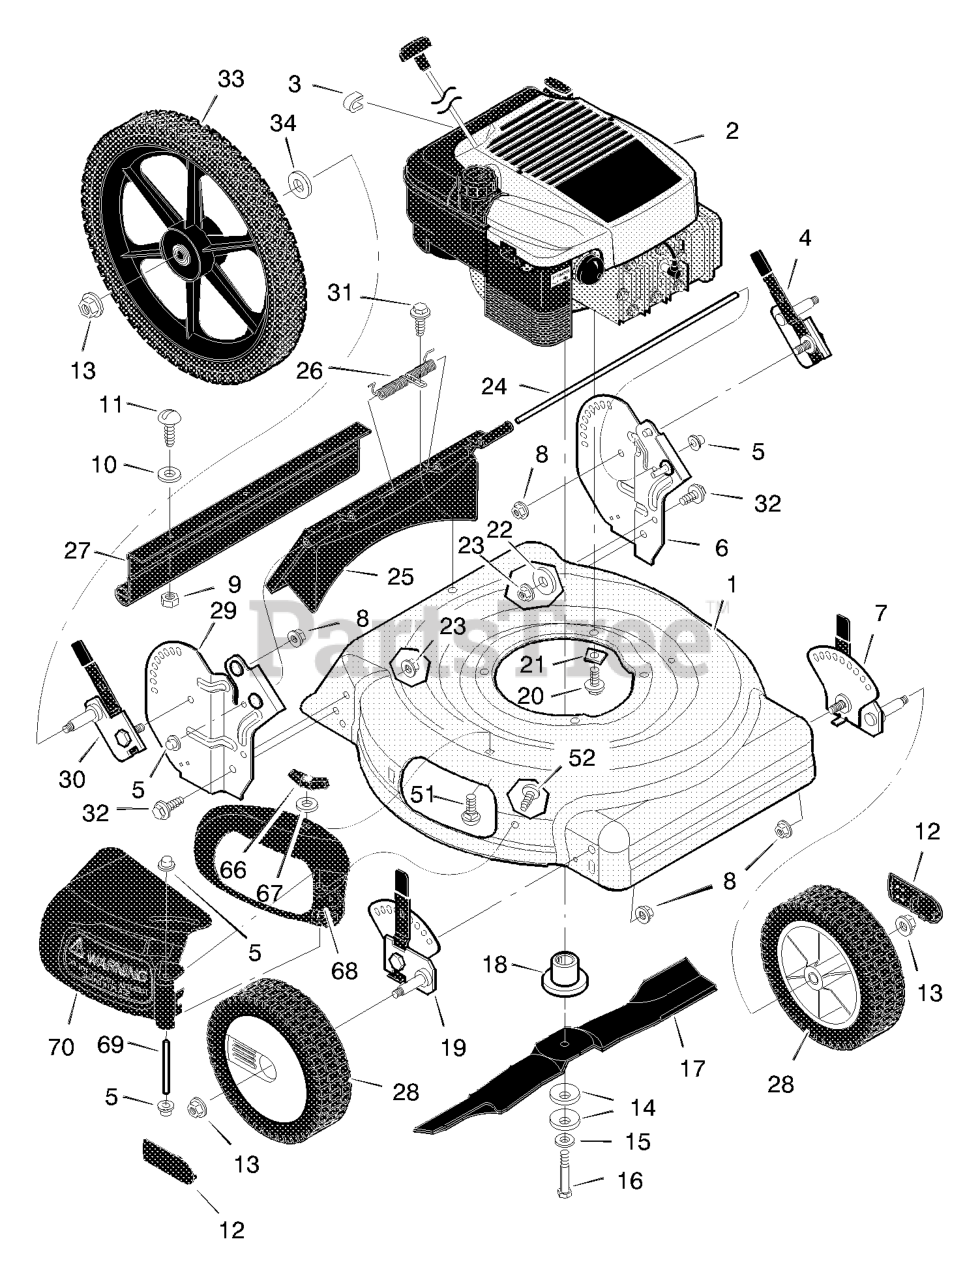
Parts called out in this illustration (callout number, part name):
1	Housing
2	Engine *
3	Stop, Rope (Recoil - Start)
4	Adjuster, Left Height
5	Push On Cap
6	Bracket, Left Handle
7	Adjuster, Left Front Height
8	Nut, Flange
9	Nut, Hex
12	Hub Cap
13	Nut, Flange
14	Washer, Belleville
18	Adapter, Blade
19	Adjuster, Right Front Height
20	Bolt, Engine
21	Support, Engine
22	Washer
23	Nut, Flange
24	Rod, Pivot
25	Door, Rear
27	Guard, Rear
28	Wheel
29	Bracket, Right Handle
30	Adjuster, Right Height
32	Bolt
33	Wheel, Rear
51	Bolt, Carriage
66	Wingnut
67	Retainer, Push
69	Pin, Pivot
70	Deflector, Chute
